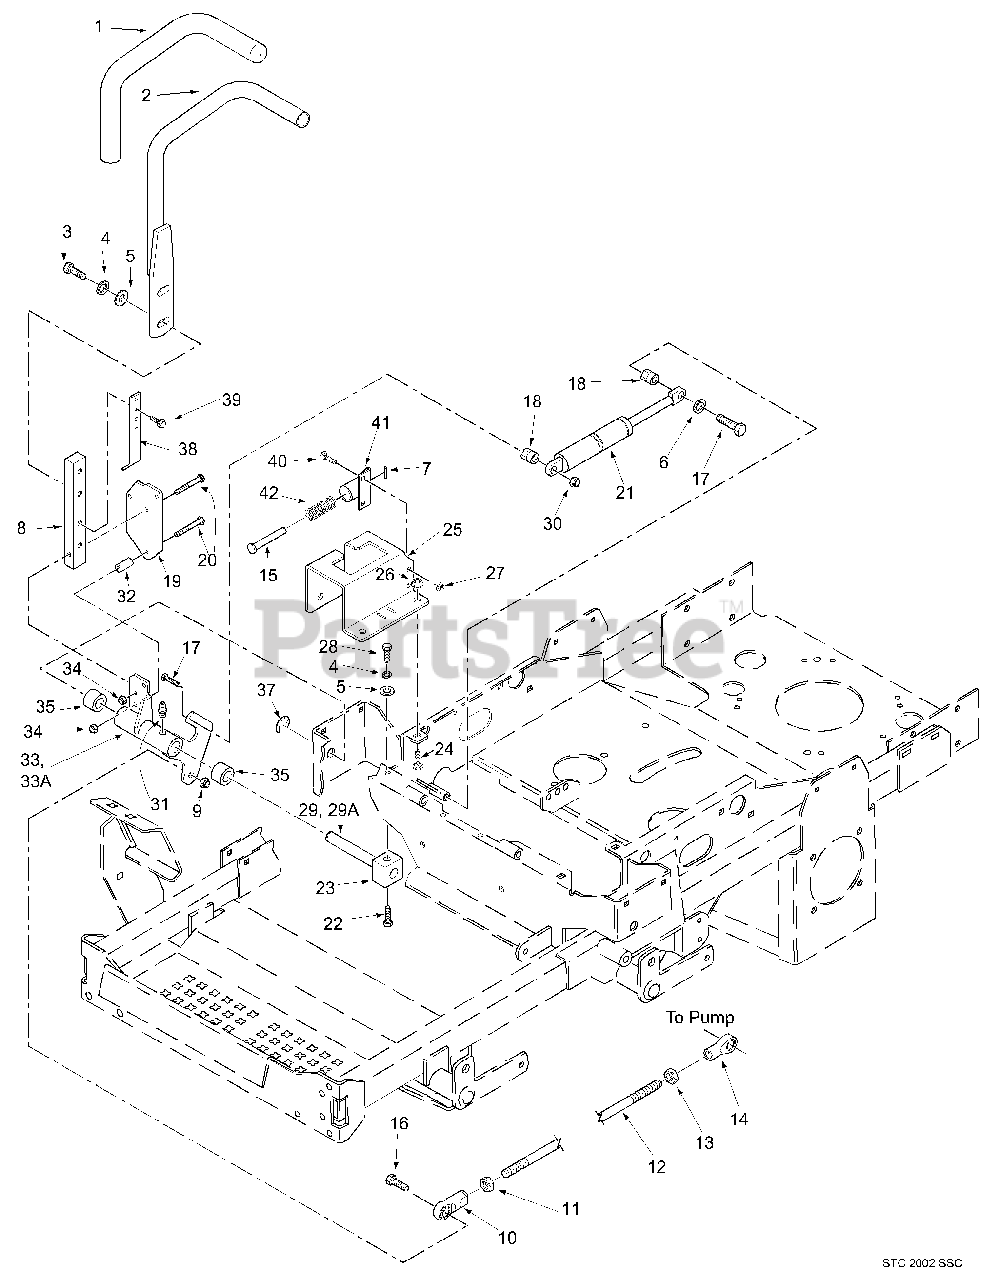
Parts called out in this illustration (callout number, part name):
1	Grip, Control Lever
2	Handle Bar
3	Bolt, Hex Head 3/8-16 x 1-1/4"
4	Lock Washer, 3/8"
5	Flatwasher, 3/8-.391 x .938 x .105
6	Washer
7	Roll Pin, Spring 5/32 x 3/4"
8	Bar, Control Lever
9	Nut, Elastic Stop 3/8-16
10	Rod End, 3/8-24 RH Female
11	Nut, 3/8-24 RH Thread
12	Rod, Pump Control Linkage
13	Nut, 3/8-24 UNF-2B LH Thread
14	Rod End, 3/8-24 LH Thread
15	Pin Retainer
16	Bolt, Hex Head 3/8-16 x 1-1/2"
17	Bolt, Hex Head 5/16-18 x 1-3/4"
18	Spacer, Pump Dampener
19	Plate, Control Lever
20	Bolt, Hex Head 5/16-18 x 2"
21	Gas Damper
22	Bolt, Hex Head 3/8-16 x 1"
23	Block, Clamping
24	Bolt, Carriage, 5/16-18 x 3/4"
25	Control Plate - LH
26	Nut, Serr., Flange, 5/16-18
27	Nut, Elastic Stop 1/4-20
28	Bolt, Hex Head 3/8-16 x 3/4"
29	Shaft, Steering Control
29A	Block, Clamp
30	Nut, Elastic Stop 5/16-18
31	Grease Fitting, 1/4-28 Self Tap
32	Spacer, Control
33	Control Lever Assy RH
34	Nut, Elastic Stop 5/16-18
35	Bushing
37	Retaining Ring, 3/4" Ext.
38	Bracket, Switch Actuator
39	Bolt, Hex Serr. Flange 5/16-18 x 3/4"
40	Bolt, Carr. 1/4-20 x 3/4"
41	Bracket, Control Return
42	Spring
